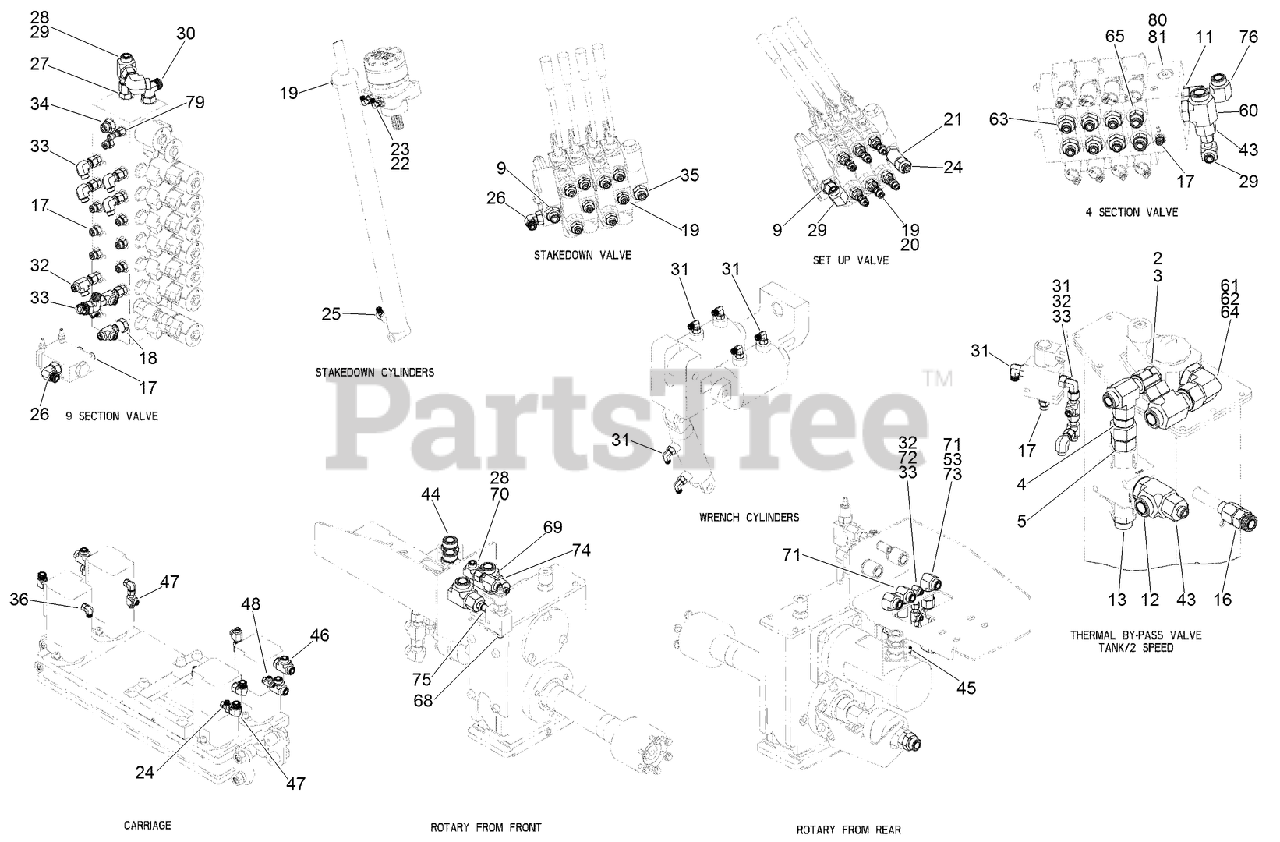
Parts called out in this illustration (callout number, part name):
2	CONNECTION - Straight, -12 ORFS / -8 ORB
3	FITTING-TEE
4	CONNECTION - Adapter, -12 ORB / -12 ORFS
5	FITTING-STRAIGHT
9	CONNECTION - Straight, -8 ORFS / -10 ORB
11	CONNECTION - Straight, -12 ORFS / -12 ORB
12	CONNECTION - Run Tee, -16 ORFS / -16 ORB
13	CONNECTION - Straight, -12 ORFS / -16 ORB
16	FITTING-STRAIGHT
17	CONNECTION - Straight, -4 ORFS / -6 ORB
18	FITTING-STR,ORIF
19	CONNECTION - Straight, -4 ORFS / -8 ORB
20	FITTING-STRAIGHT
21	CONNECTOR
22	CONNECTION - 90 Deg, -4 ORFS / -4 ORB
23	REDUCER-STRAIGHT, THREADED
24	CONNECTION - 90 Degree, -4 ORFS / -4 ORB
25	CONNECTION - 90 Deg, -4 ORFS / -8 ORB
26	CONNECTION - 90 Deg, -6 ORFS / -8 ORB
27	CONNECTION - Straight, -8 ORFS / -8 ORB
28	CONNECTION - Run Tee, -8 ORFS / -8 ORFS
29	CONNECTION - 90 Deg, -8 ORFS / -8 ORFS
30	CONNECTION - 90 Deg, -8 ORFS / -8 ORB
31	CONNECTION - 90 Deg, -4 ORFS / -6 ORB
32	CONNECTION - Run Tee, -4 ORFS / -4 ORFS
33	CONNECTION - 90 Deg, -4 ORFS / -4 ORFS
34	CONNECTION - Straight, -6 ORFS / -8 ORB
35	CONNECTION - Straight, -6 ORFS / -10 ORB
36	CONNECTION - 90 Deg, -6 ORFS / -6 ORB
43	FITTING-REDUCER
44	CONNECTION - Straight, -16 ORFS / -16 ORB
45	CONNECTION - Straight, -8 ORFS / -6 ORB
46	CONNECTION - Run Tee, -10 ORFS / -10 ORB
47	CONNECTION - 90 Deg, -10 ORFS / -10 ORB
48	CONNECTION - Run Tee, -4 ORFS / -4 ORB
53	FITTING-TEE
60	CONNECTION - Branch Tee, -16 ORFS / -16 ORB
61	CONNECTION - 90 Degree, -16 ORFS / -20 ORB
62	FITTING-TEE
63	CONNECTION - Straight, -8 ORFS / -12 ORB
64	FITTING-REDUCER
65	CONNECTION - Straight, -10 ORFS / -12 ORB
68	CONNECTION - Straight, -6 ORFS / -6 ORB
69	FITTING-TEE, BULKHEAD
70	CONNECTION - Run Tee, Bulkhead, -8 ORFS / -8 ORFS
71	CONNECTION - 90 Degree, Bulkhead, -10 ORFS / -10 ORFS
72	CONNECTION - 90 Degree, Bulkhead, -4 ORFS / -4 ORFS
73	CONNECTION - 90 Degree, -10 ORFS / -10 ORFS
74	FITTING-REDUCER
75	CONNECTION - Straight, -6 ORFS / -6 ORB
76	CONNECTION - 90 Deg, -12 ORFS / -12 ORFS
79	COUPLING - Quick Disconnect
80	CONNECTION - Straight, -8 ORFS / -8 ORB
81	COUPLING - Quick Disconnect
